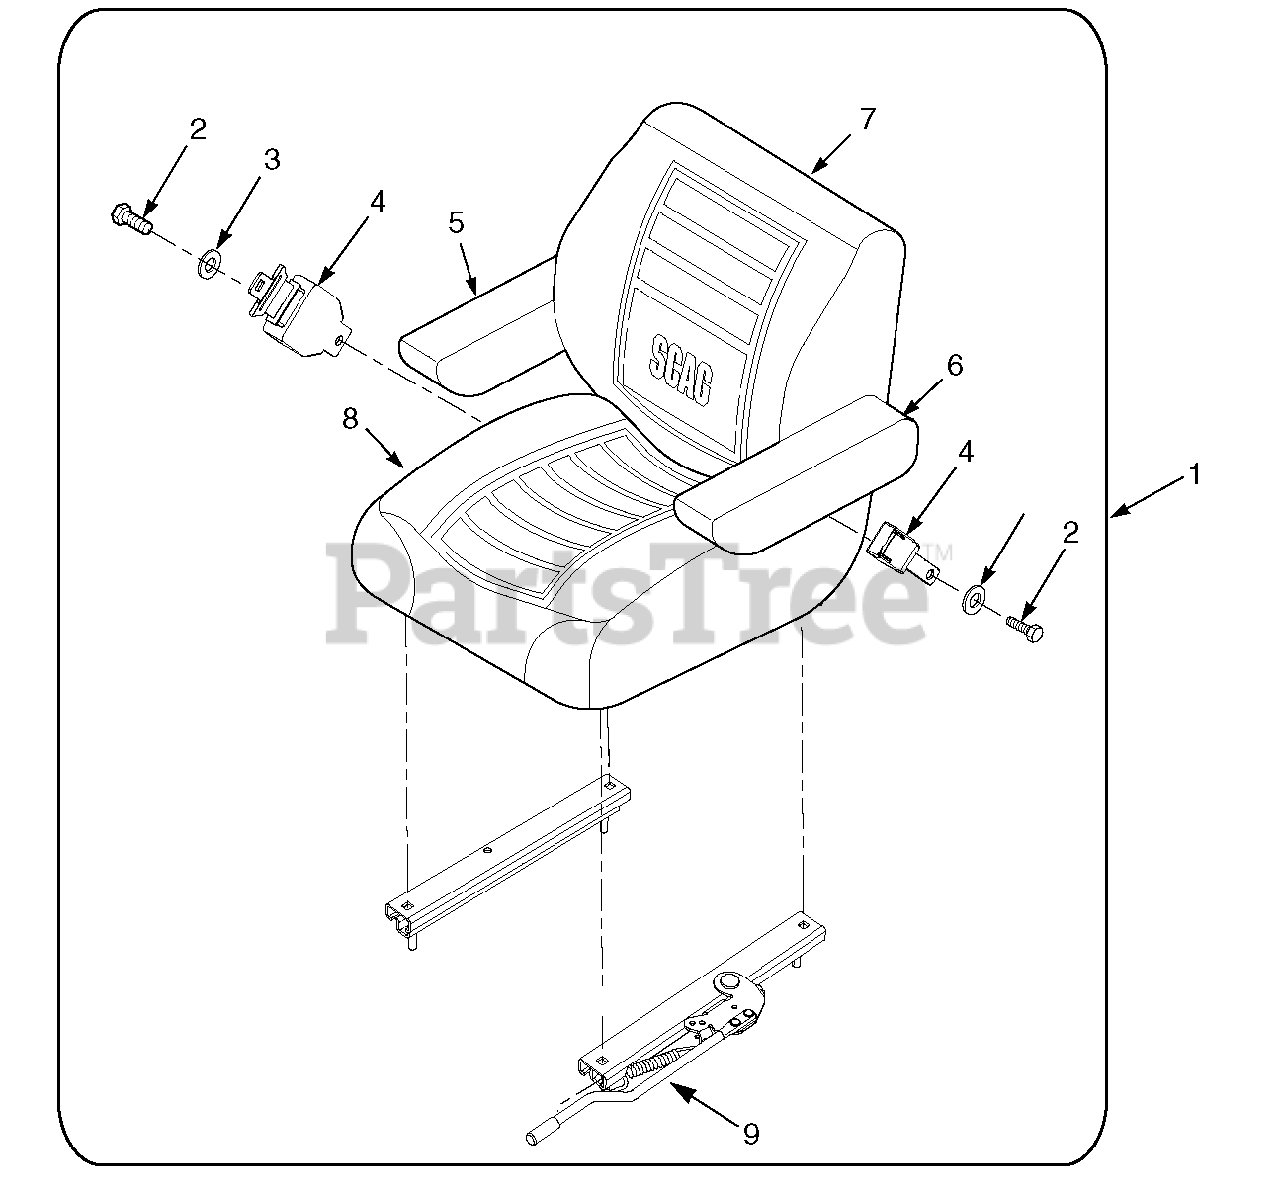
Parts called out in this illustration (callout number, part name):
1	Seat Assembly
2	Bolt, Hex Head 7/16-20 x 1"
3	Flatwasher, 7/16-.500 x 1.25 x .083
4	Retractable Seat Belt
5	Armrest, RH
6	Armrest, LH
7	Cover, Backrest
8	Cover, Cushion
9	Seat Track Set
